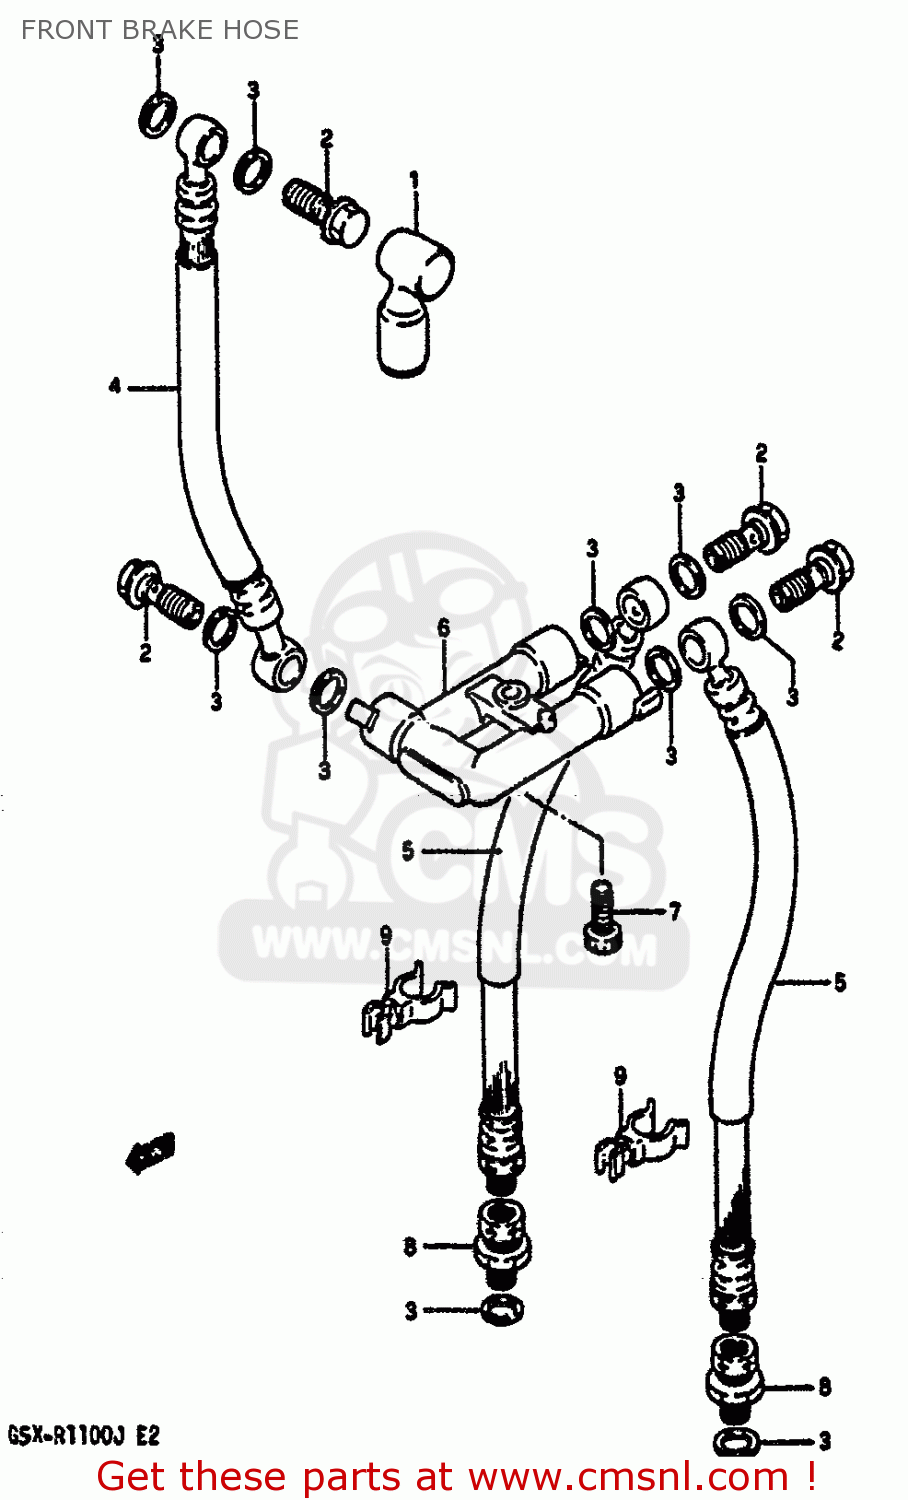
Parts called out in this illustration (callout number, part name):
1	BOOT,MASTER CYLINDER
2	BOLT UNION
3	WASHER(10X15X1.5)
4	HOSE,FRONT BRAKE NO.1
5	HOSE,FRONT BRAKE NO.2
6	JOINT,BRAKE HOSE
7	BOLT
8	ADAPTER,BRAKE HOSE
9	CLAMP
